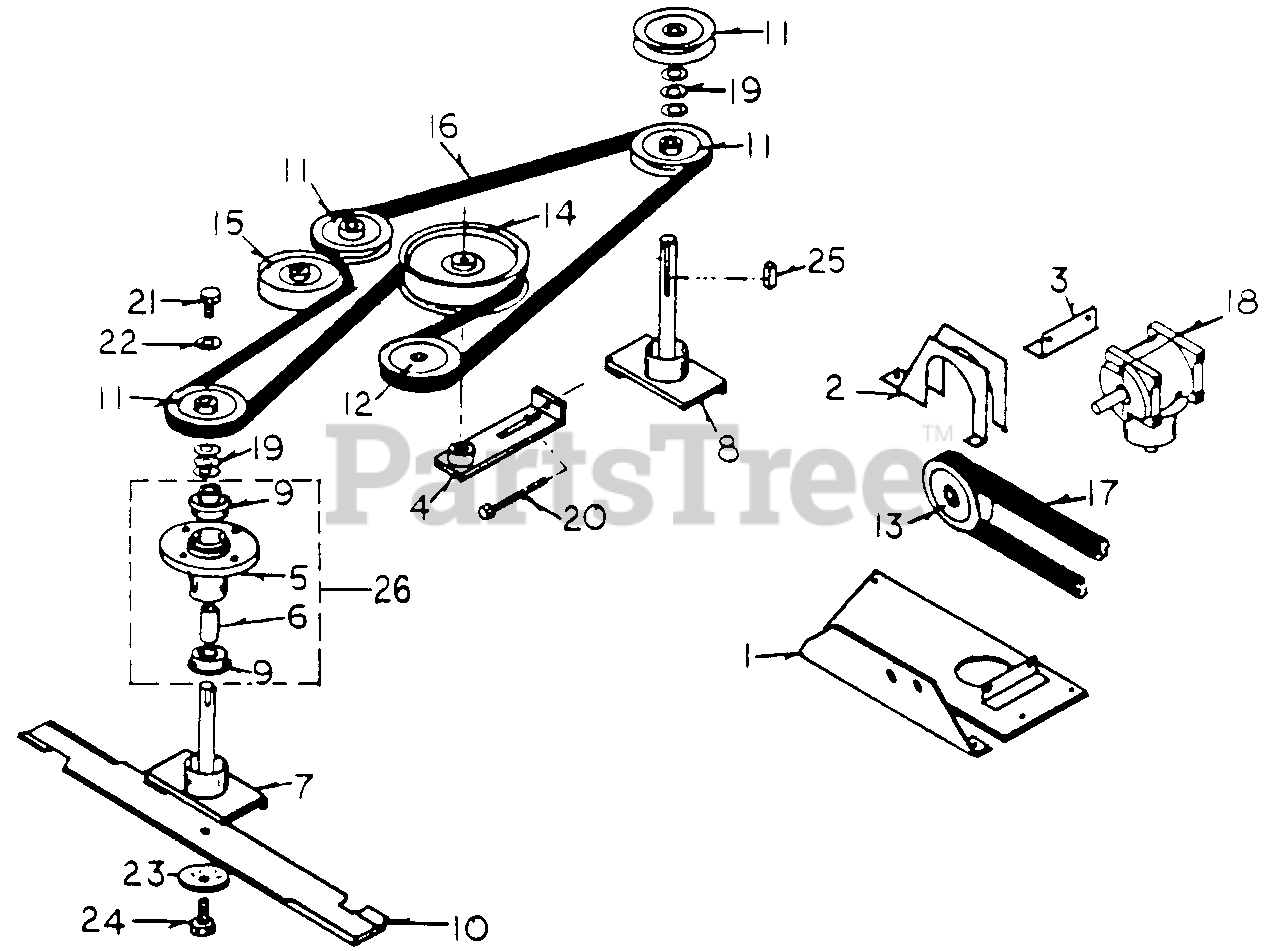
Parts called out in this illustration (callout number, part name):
2	Belt Guard
3	Gearbox Mount Angle
4	Belt Tightener
5	Splndle Housing
6	Spindle Spacer
7	Splndle Shaft
8	Spindle Shaft, Long
9	Spindle Bearing
11	Spindle Pulley
12	Gearbox Pulley, Output
13	Gearbox Pulley, Input
14	Idler Pu1ley, Large
15	Idler Pulley, Small
17	Deck Drive Belt
20	Adjustment Bolt
21	Hex Ny-Lock Bolt, 5/16-24 x 3/4'
22	Washer, 5/16", 10GA
24	Hex Bolt, 3/8-24 x 1 1/14"
25	Key Stock, 3/16"
26	Spindle Houging Assembly
